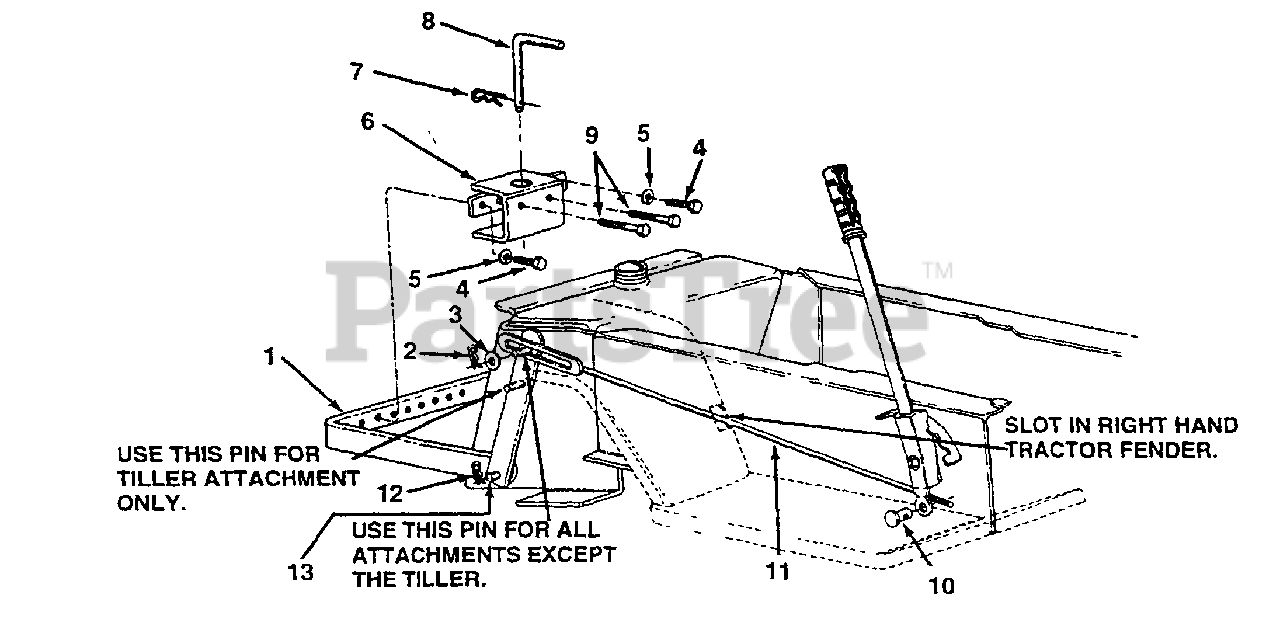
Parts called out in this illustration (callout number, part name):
3	Fl-Wash. 1/2" I.D.
4	Hex Bolt 1/2-13 x 1.0" Lg.
5	L-Wash. 1/2" l.D.
8	Hitch Pin
9	Hex Bolt 1/2-13 x 3.0" Lg."
10	Adjustment Ferrule
13	Hitch Rod
